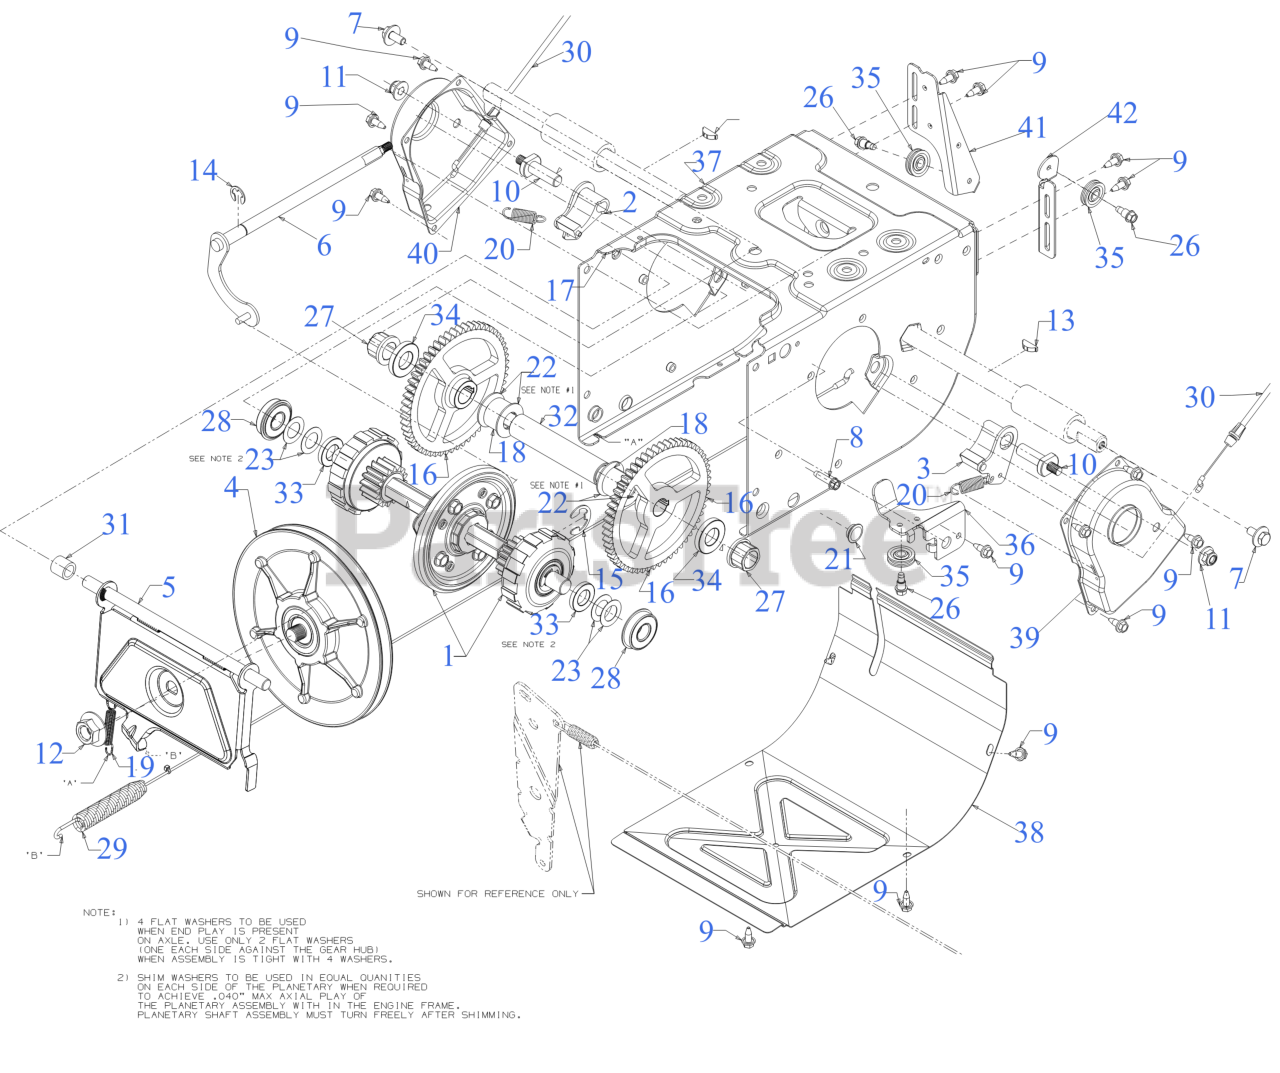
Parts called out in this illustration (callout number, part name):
1	PLANETARY FRICTION WHEEL HEX SHAFT
2	DOGG ASSEMBLY (RH)
3	DOGG ASSEMBLY (LH)
4	FRICTION WHEEL DISC ASSEMBLY
5	FRICTION WHEEL BRACKET (POWDER BLACK)
6	SHIFT ROD ASSEMBLY
7	SCREW 5/16-24 x .750 GR5
8	SCREW 1/4-20 x 1.00
9	SCREW 1/4-20X.625
10	ACTUATOR SHAFT
12	FLANGE NUT 5/8-18
13	KEY 3/16 x 3/4
14	E-RING FOR .500 SHAFT
15	RETAINING RING
18	SPACER: .76ID x .75
19	EXTENSION SPRING
20	EXTENSION SPRING
22	FLAT WASHER
23	FLAT WASHER .67X 1.174X .02
26	SHOULDER SCREW
27	FLANGE BEARING
28	BALL BEARING W/RET
29	WHEEL DRIVE CABLE 44.955"
29	EXTENSION SPRING .55 x 6.25
30	STEERING CABLE
31	SPACER-.513 ID x .703 OD x .69
32	AXLE SUPPORT TUBE
34	AXLE SPACER
35	CABLE GUIDE ROLLER
36	AUGER CABLE BRACKET
37	DRIVE FRAME
41	CABLE GUIDE BRACKET (DRIVE)
42	CABLE GUIDE BRACKET (AUGER)
